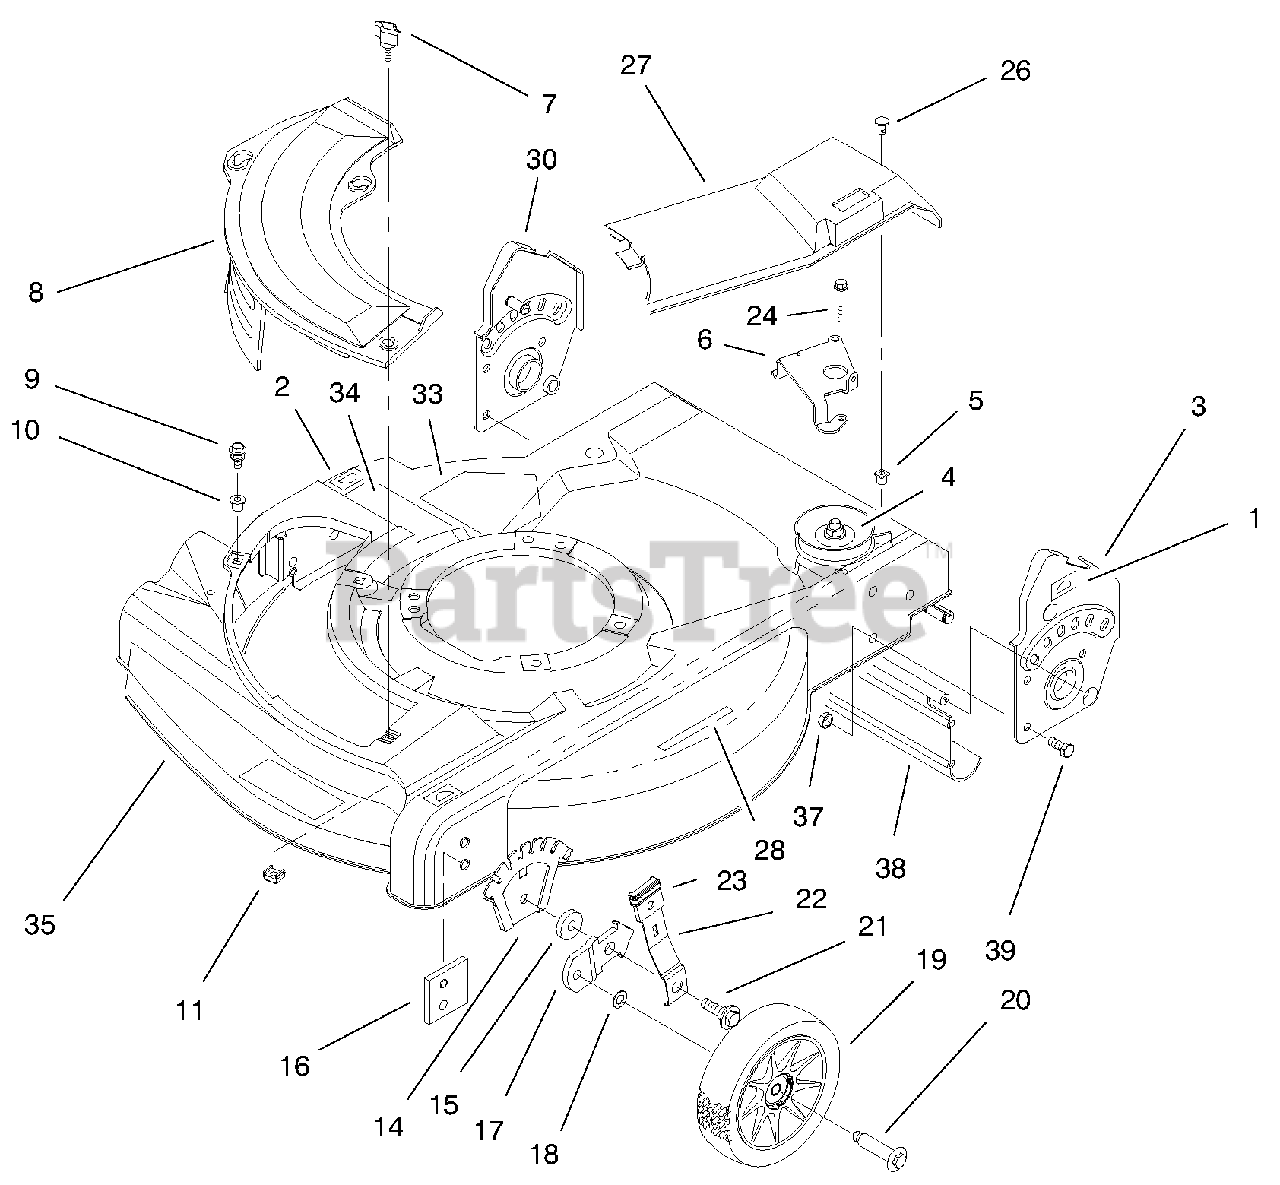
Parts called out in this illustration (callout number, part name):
1	Decal-HOC
2	Decal-HOC
3	ASM-Handle Bracket
4	ASM-Gear Case
5	Grommet
6	Guide-Transmission
7	Knob-Cover Plate
8	Mulch Plate-21"
9	Screw-Sems
10	Grommet-Plastic
11	Nut-Cage
14	Plate-Height Adjust
16	Plate-Baffle
17	Bracket-Wheel Height Adj
19	ASM-Wheel & Tire 6"
20	Bolt-Shoulder
21	Bolt-Shoulder
22	Spring Arm-Front
23	Knob-Height Adjust
24	Torx Head Cap Screw
26	Screw-Phil
27	Cover-Drive
28	Decal-Warning
30	ASM-Handle Bracket
33	Decal-Danger
34	Decal-Discharge
35	ASM-Housing & Baffle
37	Nut-Lock
38	Shield-Trailing
39	Screw-HH
